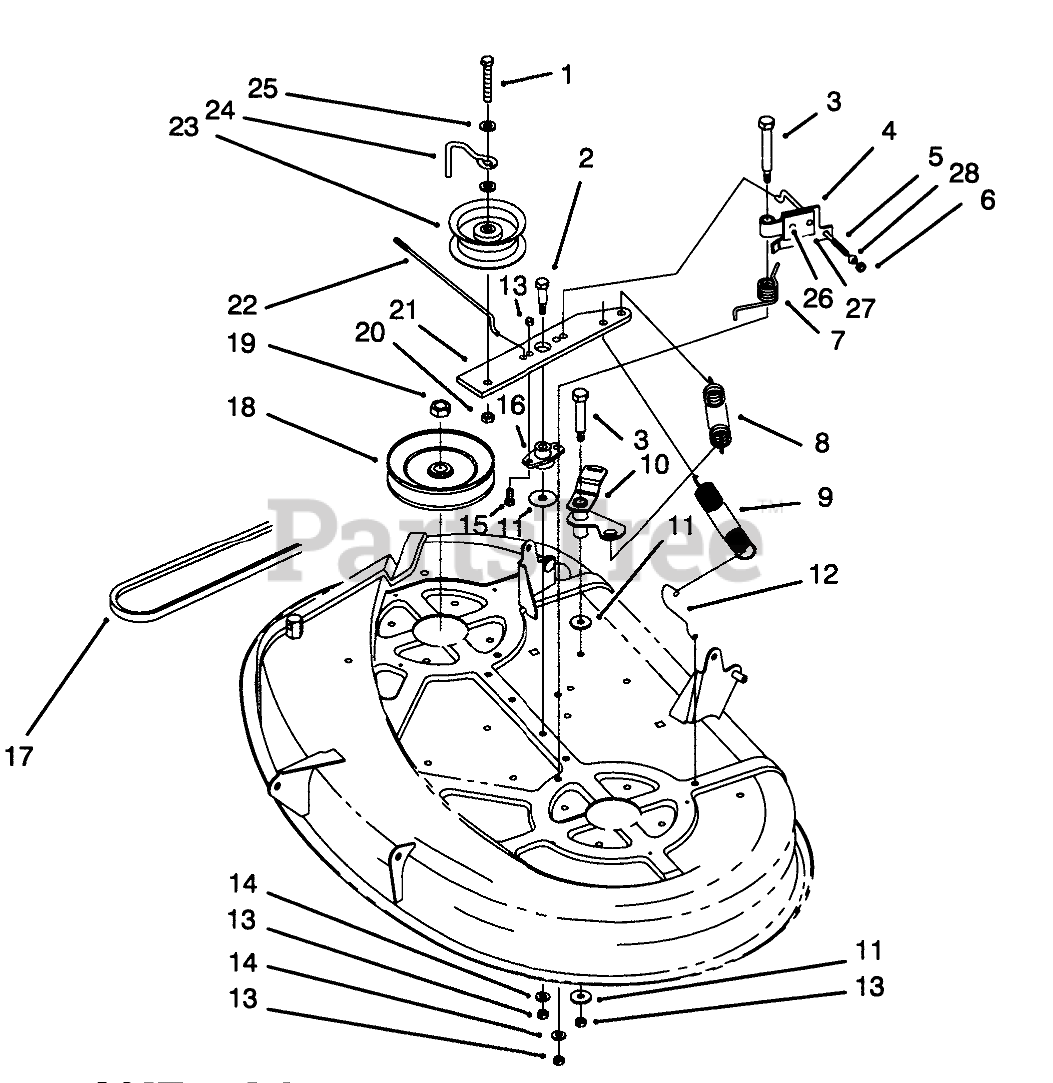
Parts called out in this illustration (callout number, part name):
1	SCREW-HH
2	SCREW-SHOULDER, HH
3	BOLT-SHOULDER
4	Brake-Deck (Incl. Ref. #26 & 27)
5	ROD-BRAKE, DECK LH
6	NUT-LOCK, NI
7	SPRING-TORSION
8	SPRING-DECK, ENGAGEMENT
9	SPRING-EXTENSION
10	Bellcrank
11	WASHER-FLAT
12	HOOK-RETURN, SPRING
13	NUT-LOCK, NI
14	WASHER-PLAIN
15	SCREW-HH
16	BUSHING-ARM, IDLER
17	BELT-V
18	PULLEY
19	NUT-HEX
20	NUT-LOCK, NI
21	Arm-Idler
22	ROD-BRAKE, DECK RH
23	PULLEY-IDLER, FLAT
24	GUIDE-IDLER, BELT
25	WASHER-FLAT
26	RIVET-BLIND
27	PAD-BRAKE
28	BALL-SWIVEL, STOP
